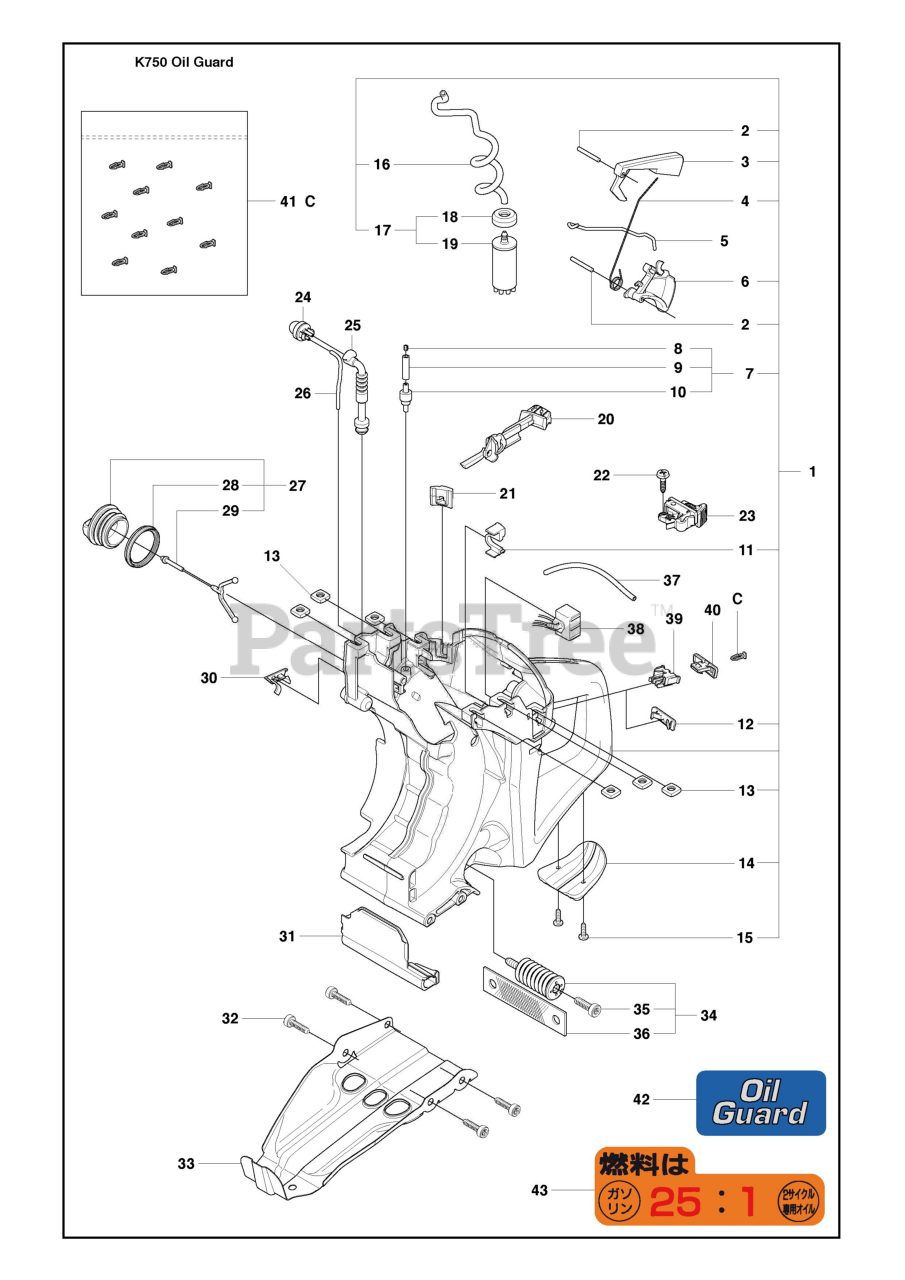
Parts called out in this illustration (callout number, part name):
1	Fuel Tank
2	Parallel Pin
3	Throttle Lockout
4	Spring
5	Throttle Rod
6	Throttle Trigger
7	Tank Vent Assy
8	Sinter Plug
14	Ground Support
16	Fuel Hose
17	Fuel Filter
18	Hose Clamp
19	Fuel Filter
20	Choke Control
23	Stop Switch
24	Primer Housing
25	Fuel Hose
26	Fuel Hose
27	Tank Cap Assy
29	Tank Cap Holder
31	Heat Shield
33	Base Plate
34	Vibration Absorber
37	Fuel Hose
38	Electronic Box
39	Housing
40	Switch
41	Kit Break Pin
42	Label
43	Label
